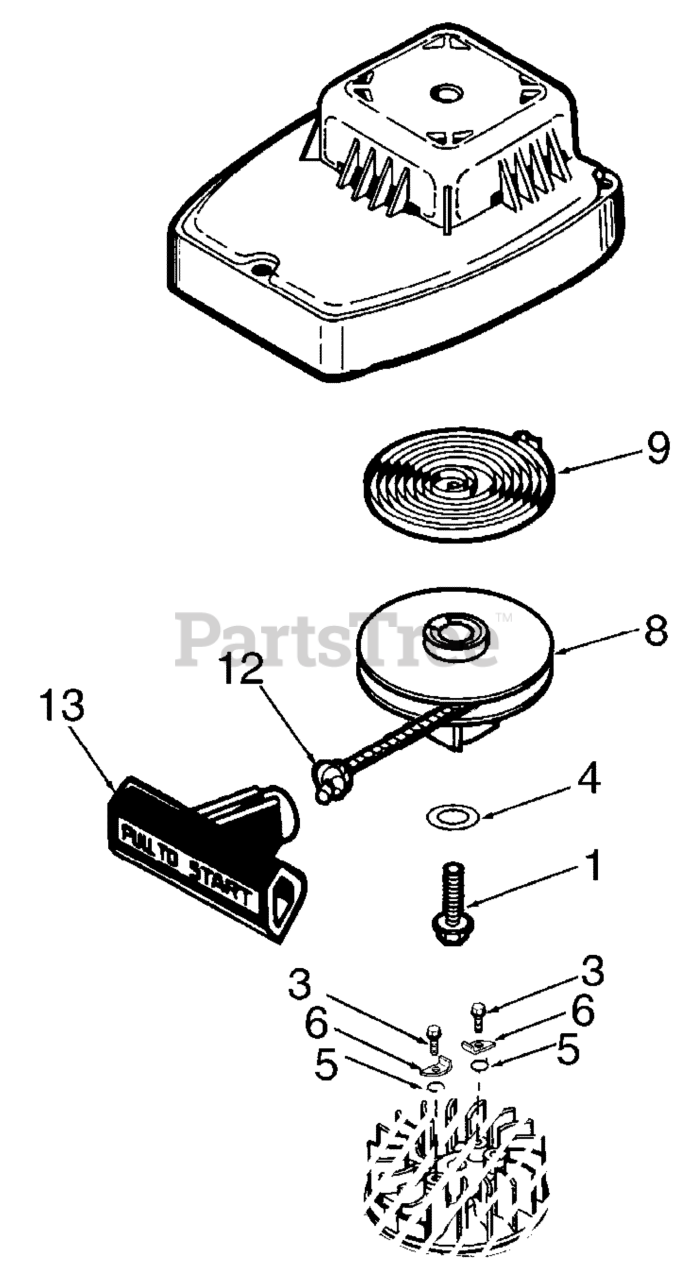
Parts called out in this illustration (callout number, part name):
1	Retainer Screw, 10-24 x 1-3/8"
3	Pawl Screw, 12-24 x 11/64"
4	Flat Washer
8	BASE, Air Cleaner
13	Starter Handle
